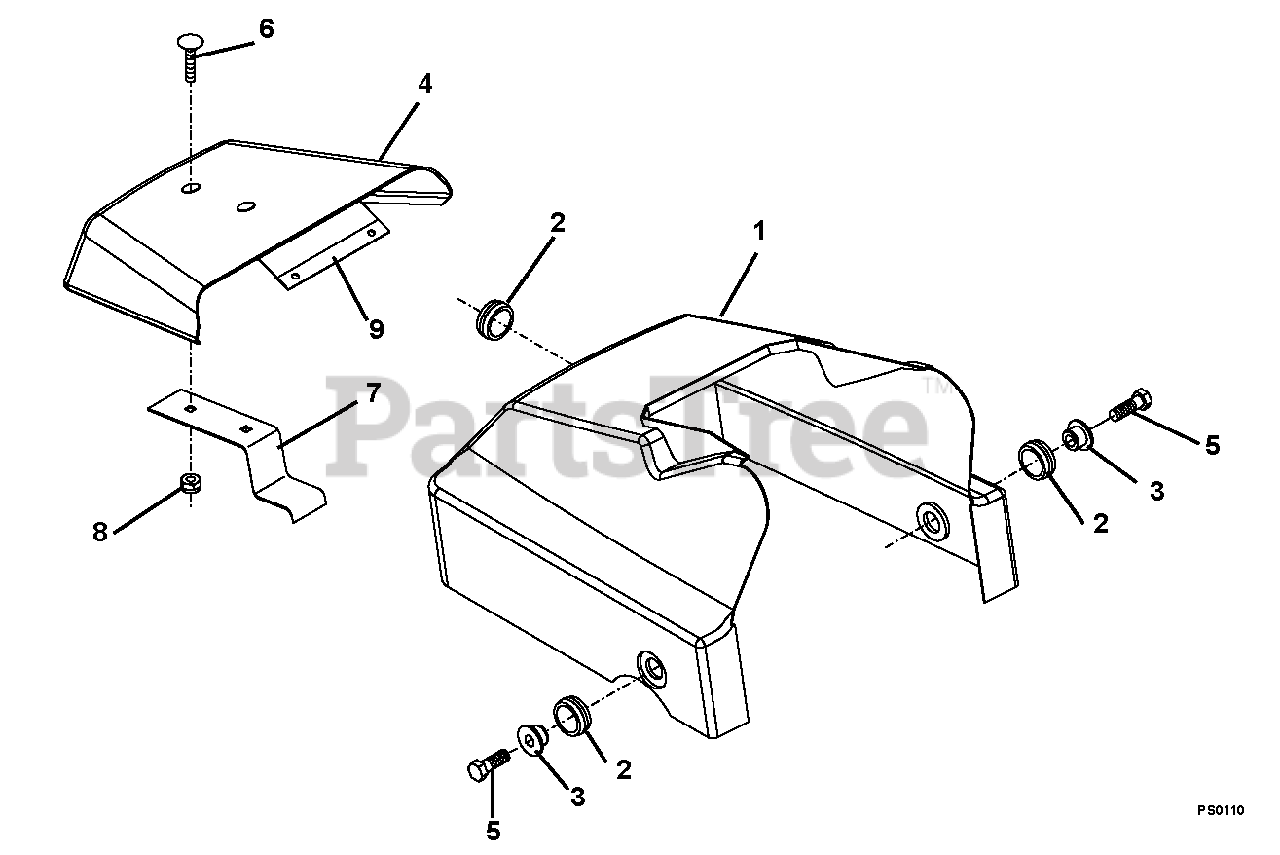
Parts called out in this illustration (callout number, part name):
1	Bonnet, Red
2	Grommet, 16/29,5 x 22/3
4	Bonnet, Red
5	Bolt, Hex, D933 Metric 8 x 25
6	Screw, CAMBED Head, D906 M6
7	Spring, Hood
8	Nut, Lock, D985 M6
